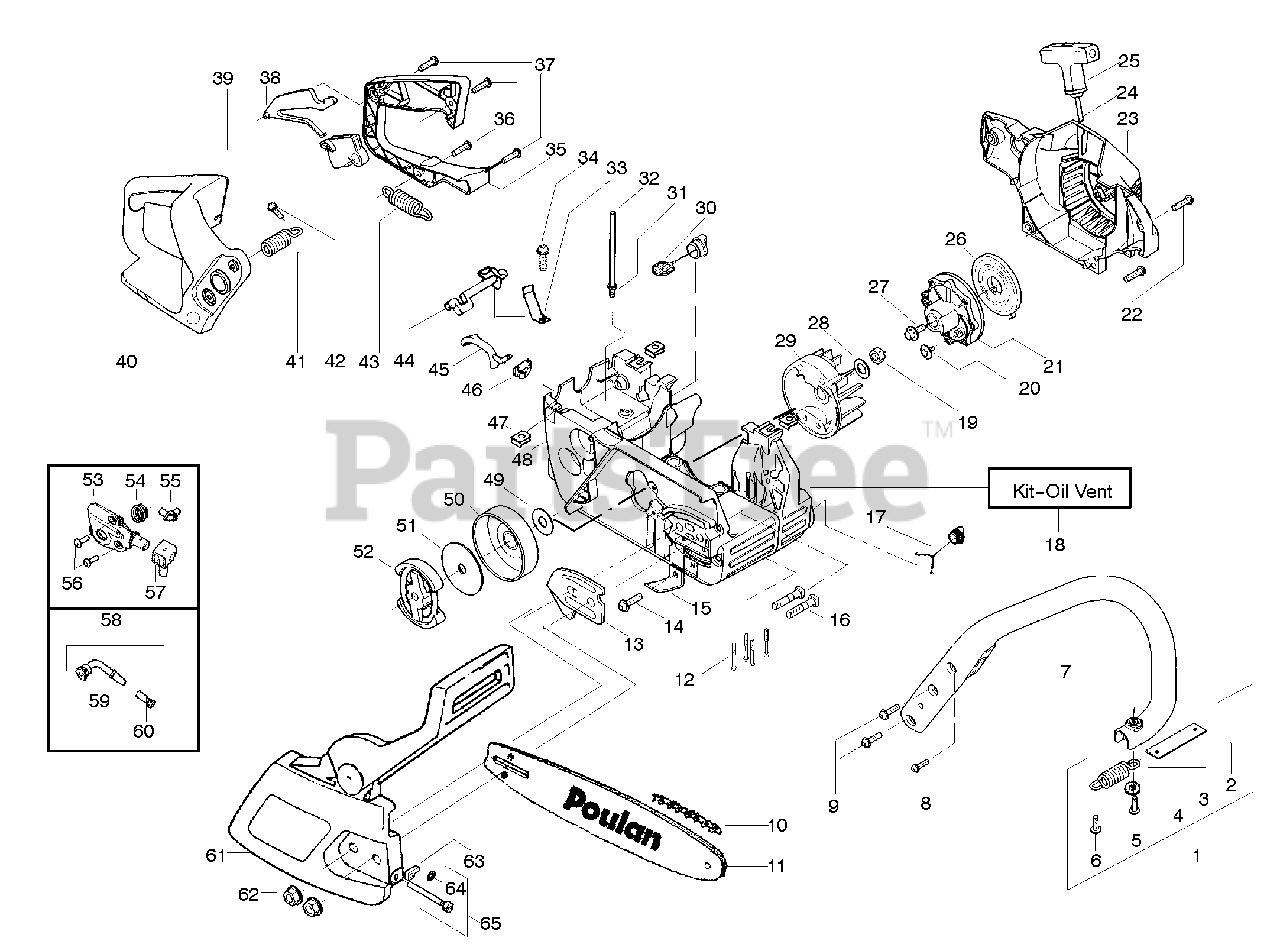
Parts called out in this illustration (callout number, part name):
1	Assy.-Isolator
2	Limiter Strap
3	Spring-Isolator
4	Washer
7	Front Handle
10	Chain - 18"
11	Bar - 18"
13	Plate-Bar Mount.
15	Chain Catcher
16	Bolt-Bar
17	Assy-Oil Cap
18	Kit-Oil Vent
19	Nut-Flywheel
21	Starter Pulley
23	Housing-Fan
24	Kit - Rope
25	Handle-Starter
26	Spring-Recoil
28	Washer-Flywheel
29	Assy-Flywheel
30	Assy-Fuel Cap
31	Fitting-fuel line
32	Kit-Fuel line (large)
33	Spring-Switch
35	Cover-Rear Handle
38	Throttle Lockout
39	Trigger-Throttle
40	Handle - Rear
41	Kit-Isolator (Upper)
43	Spring-Isolator
44	Lever-Switch
45	Lever-Choke
46	Grommet-Knob
47	Nut-"U"-Type
48	Assy-Chassis fuel lines and caps
49	Washer-Thrust
50	Assy.-Clutch Drum w/bearing
51	Washer-Clutch
52	Assy. Clutch
53	Kit - Oil Pump
54	Gear-Worm Spring
55	Elbow-Oil Pickup
57	Seal Block
58	Assy-Oil Pick-up
59	Pick-up Oiler
60	Filter-Oil
61	Assy.-Chain Brake
62	Nut-Bar Mounting
63	Pin-Bar Adjust
64	Retainer
65	Kit-Bar Adjusting
